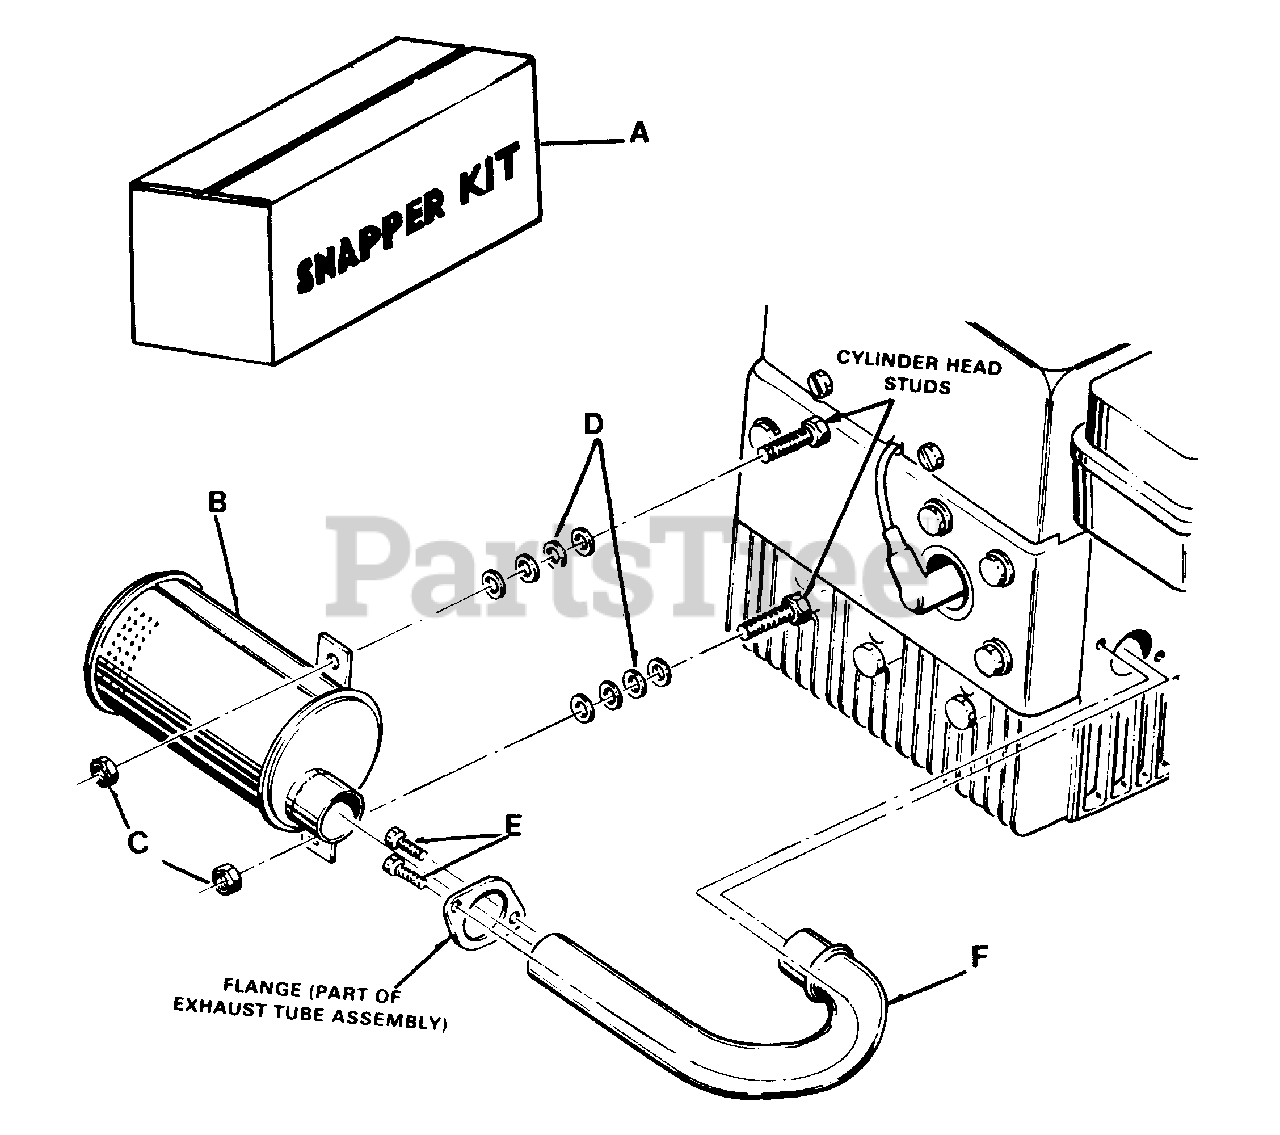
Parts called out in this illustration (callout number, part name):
A	KIT, MUFFLER
B	MUFFLER
C	NUT, 5/16C HEX
D	WASHER, 5/16 SAE
E	SCREW, HEX HEAD CAP 5/16C x 3/4
F	TUBE, EXHAUST
